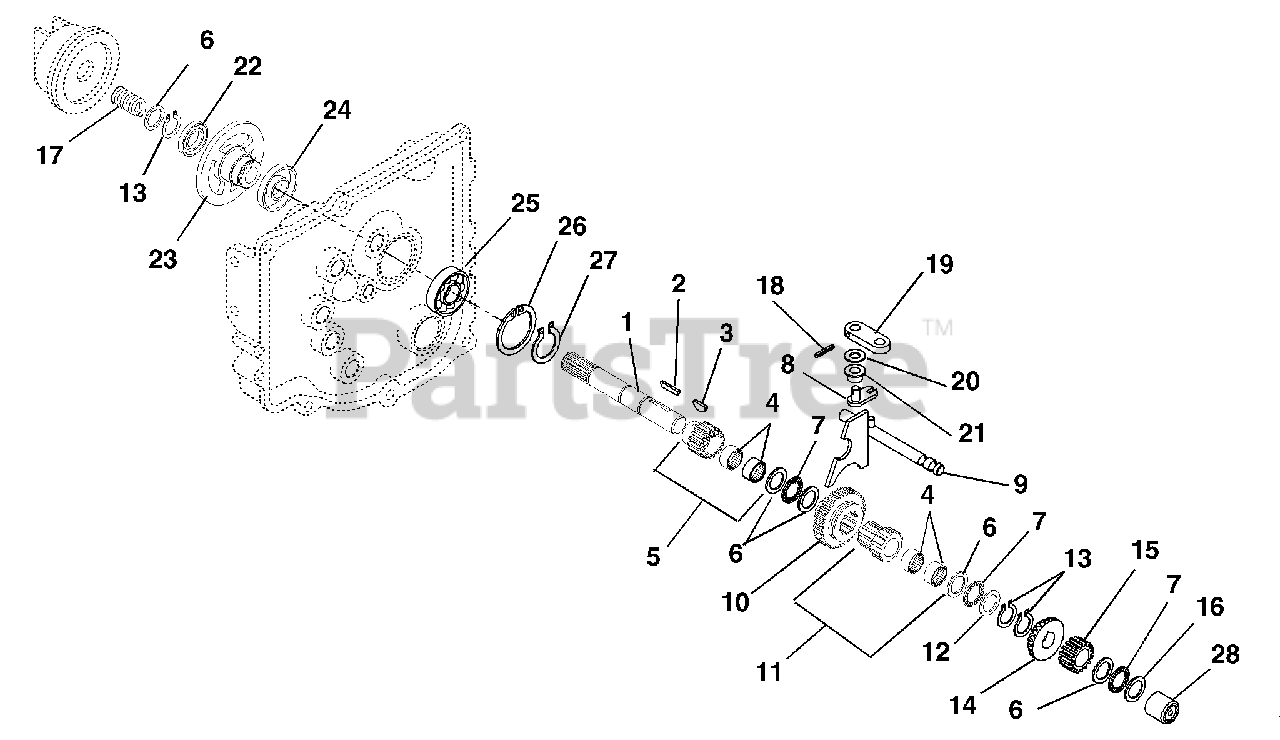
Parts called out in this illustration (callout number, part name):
1	Shaft, Forward Clutch
2	Key, Woodruff .19 x 1.25
3	Key, Woodruff .19 x .63
4	Bearing, Roller .75 x 1.00 x .50
5	Assembly, Gear and Bearing
6	Washer, Hardened-Thrust .76 x 1.23 x .031
7	Bearing, Needle Thrust .75 x 1.24 x .078
8	Weldment, Shifter
9	Weldment, Shift Rail
10	Gear, Spur 2SP 10 Diametral Pitch 36 Teeth
11	Assembly, Gear and Bearing
12	Washer, Thrust Hardened .75 x 1.24 x .062
13	Ring, Retaining-Internal .75 x .042
14	Gear, Bevel
15	Gear, 10 Diametral Pitch 16 Teeth x .75
16	Washer, Hardened-Thrust .76 x 1.25 x .094
17	Spring-Compression .085 x .80 x 1.00
18	Pin-Roll .19 x 1.00
19	Arm, Shifter
20	Washer-Felt .44 x 1.00 x .031
21	Bushing, Flange-Bronze .63 x .50 x 1.00
22	Seal .75 x 1.63 x .25
23	Hub,Clutch
24	Seal 2.25 x 3.25 x .38
25	Bearing-Ball 1.97 x 3.54 x .80
26	Ring-Retaining-Internal 3.54 x .11
27	Ring-Retaining-External 1.82 x .062
28	Bearing-Needle .75 x 1.00 x .75
